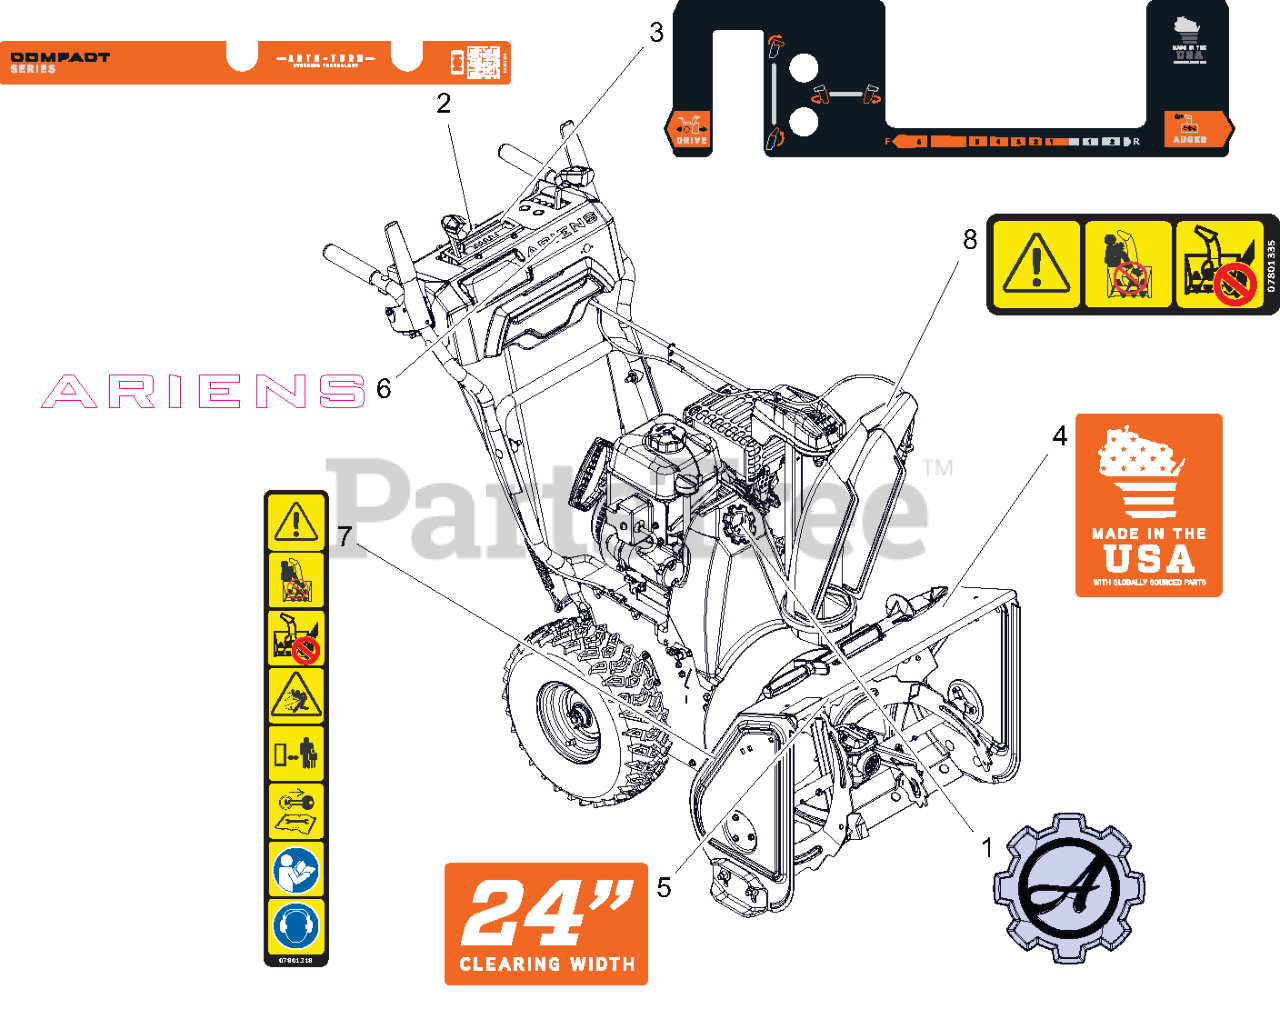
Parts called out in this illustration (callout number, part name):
1	DECAL, ARIENS - GEAR BADGE
2	DECAL- DASH - COMPACT
3	DASH- CONTROL - SMALL DASH
4	DECAL- MADE IN USA
5	DECAL- CLEARING - 24
6	DECAL- ARIENS - 7.46"
7	DECAL- SAFETY - DANGER
8	DECAL- DANGER
